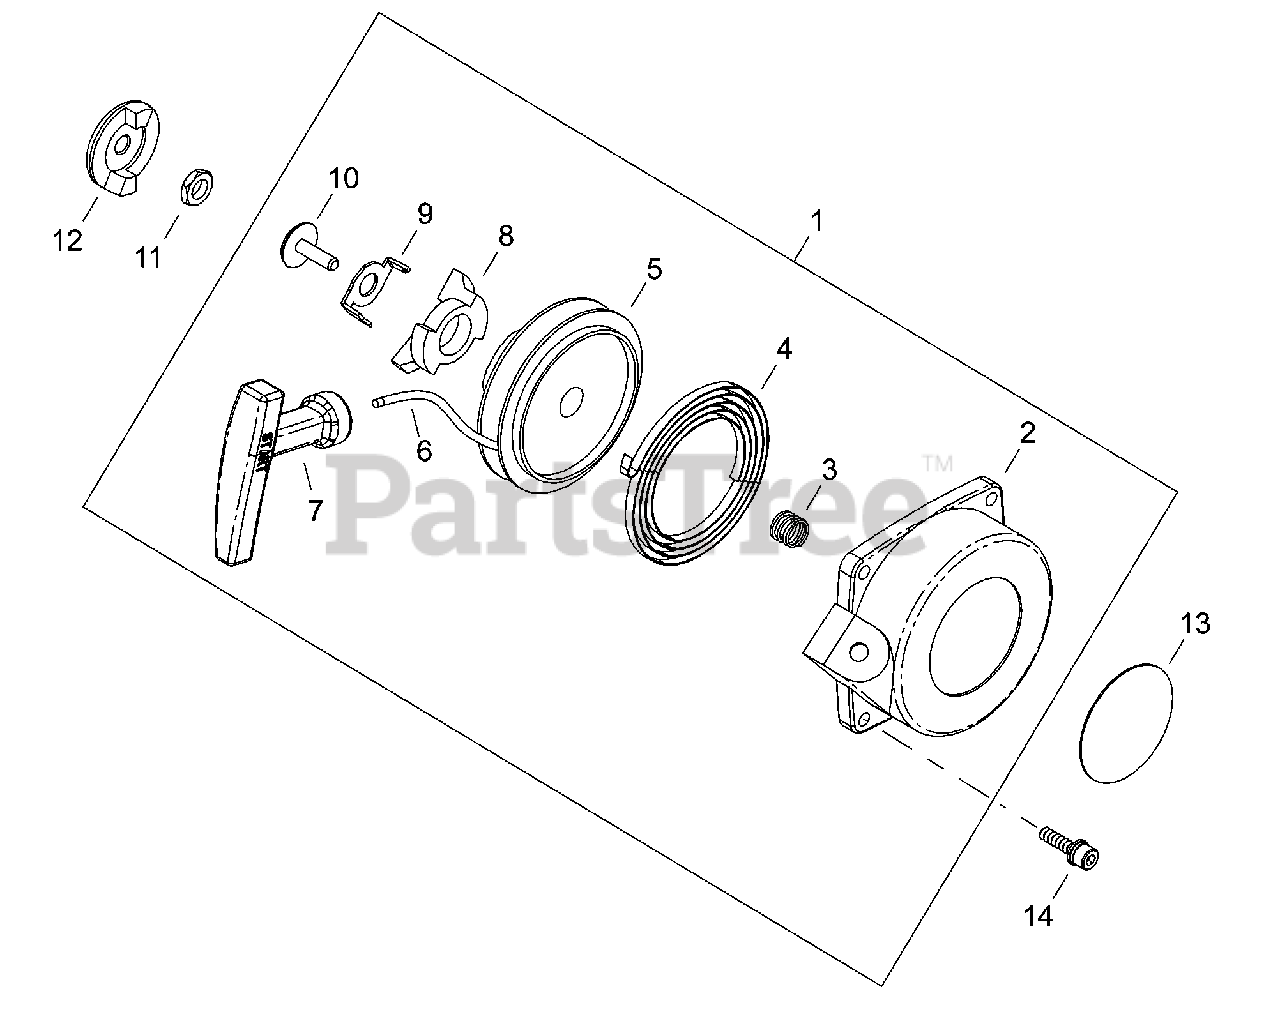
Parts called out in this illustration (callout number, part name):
1	STARTER ASSY, RECOIL
2	CASE, RECOIL STARTER
3	SPRING, PAWL
4	SPRING, RECOIL
5	REEL, ROPE
6	ROPE, STARTER
7	GRIP, STARTER
8	PAWL, STARTER
9	RETAINER
10	SCREW
11	NUT M8×1
12	PULLEY, STARTER
13	LABEL, SHINDAIWA PROFESSIONAL
14	BOLT M5×16
